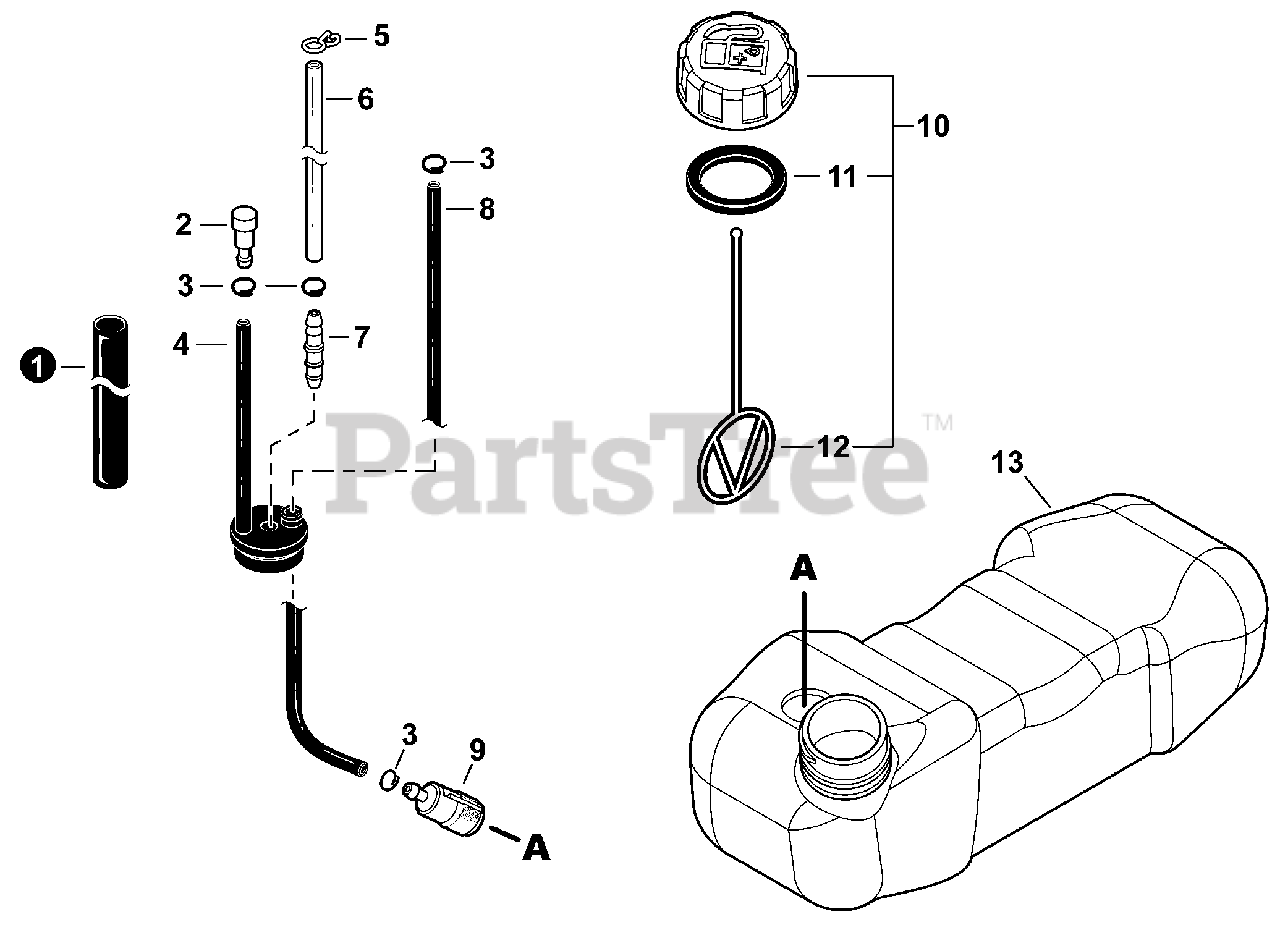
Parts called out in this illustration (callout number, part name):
1	TUBE, PROTECTIVE
2	VENT ASSY
3	CLIP Ø6
4	GROMMET, FUEL W/VENT PIPE
5	CLIP, SPRING Ø5.2
6	PIPE, FUEL 3×6×133 CLEAR
7	CONNECTOR, PIPE
8	PIPE, FUEL
9	FILTER, FUEL
10	CAP ASSY, FUEL
11	GASKET, FUEL CAP
12	CONNECTOR, CAP L= 100 MM
13	TANK, FUEL
